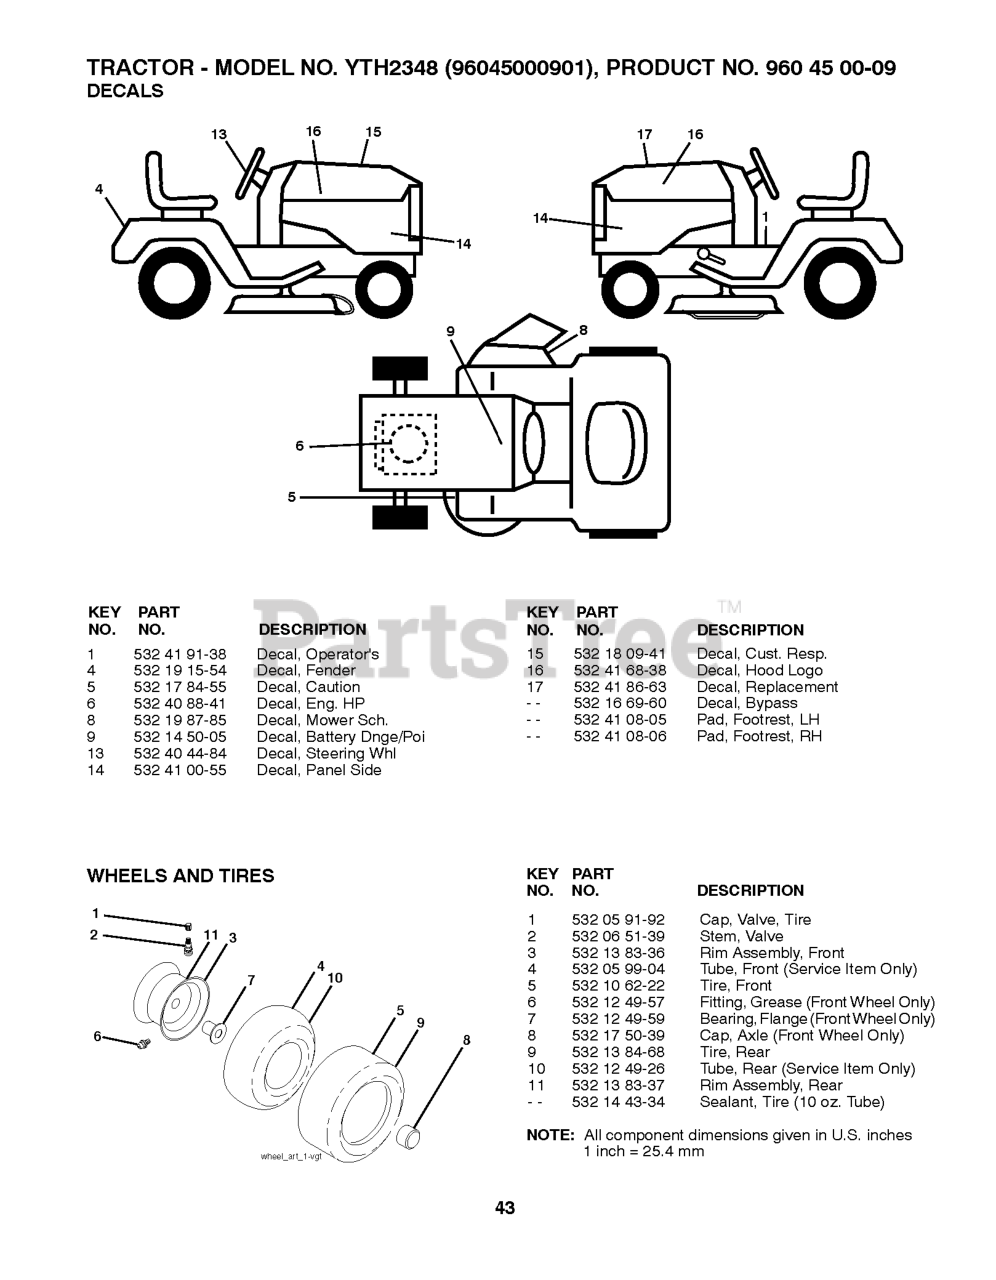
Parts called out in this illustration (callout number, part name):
1	DECAL.WARN.START.INSTRUCTIONS
4	DECAL.FENDER
5	DECAL.MOWER
6	DECAL, ENG. HP
8	DECAL.MOWER.SCH.48/54
9	DECAL BTRY SYMBOLS
13	DECAL.WHEEL.STRG.LGN.H
14	DECAL, PANEL SIDE
15	DECAL HOOD CUST. RESP.
16	DECAL.HOOD.LOGO.HUSQVARNA
17	Decal, Replacement
